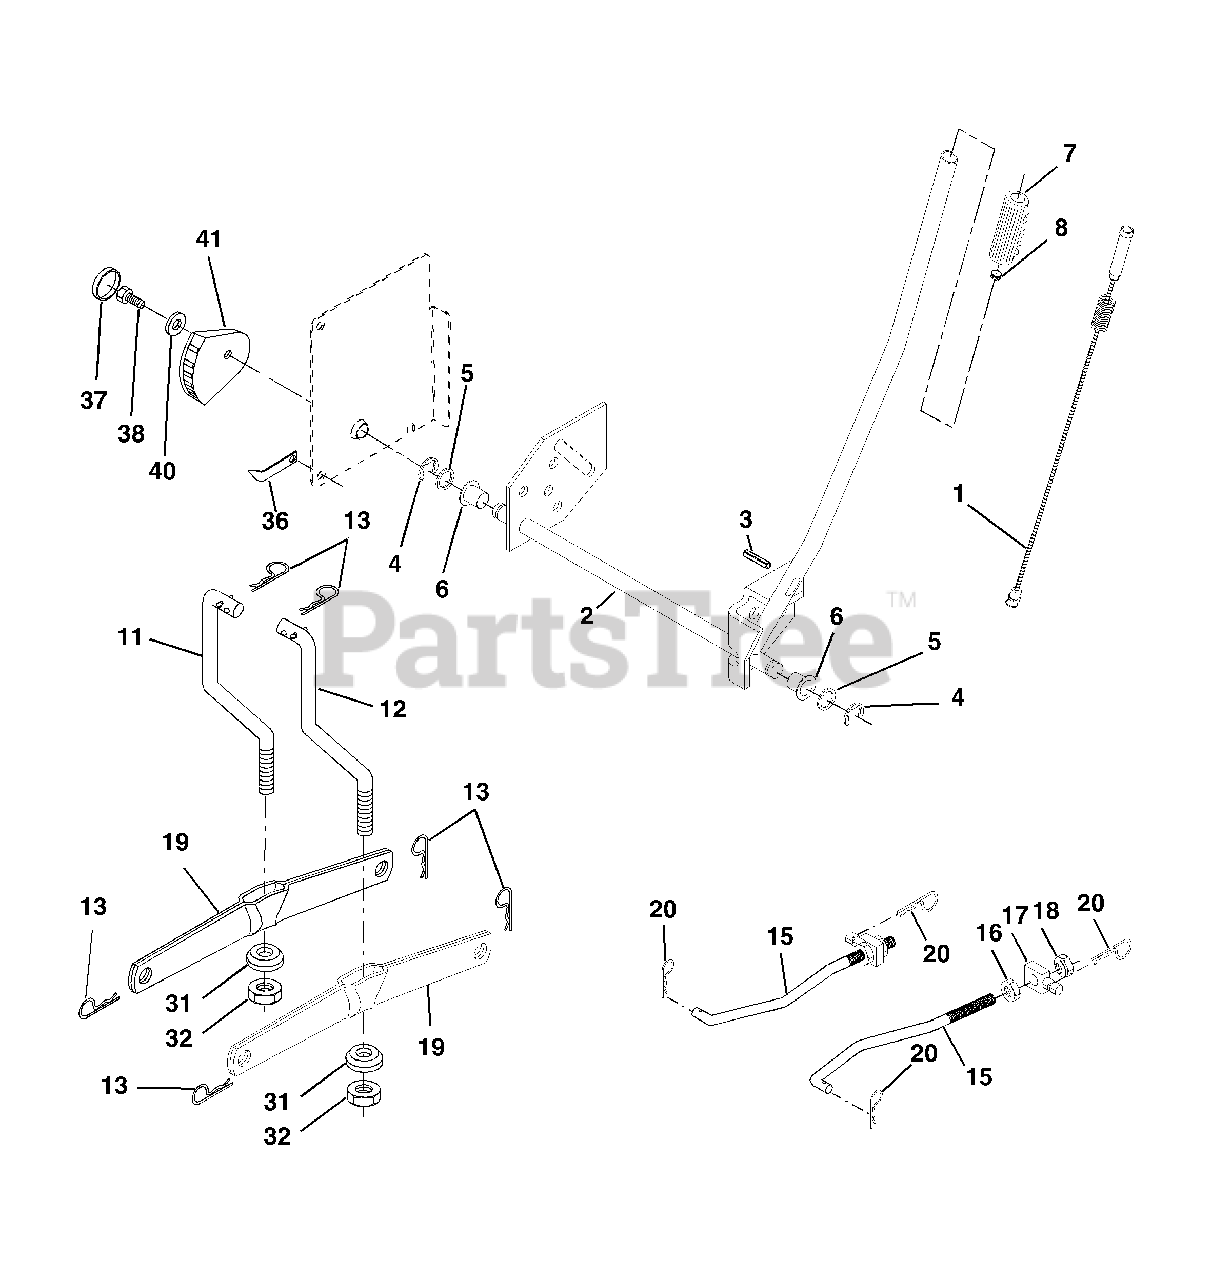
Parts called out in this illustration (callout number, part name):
1	Wire Asm Inner/Sprg W/plunger LT
2	Shaft Asm Lift RH w/Inf
3	Pin Groove 1 500 Zinc
4	E Ring #5133-62
5	Washer 21/32 X 1 X 21 Ga
6	Bearing Nylon Blk 629 Id
7	Grip Handle
8	Button Plunger Yellow
11	Link Lift LH Fixed Length
12	Link Lift RH Fixed Length
13	Retainer Spring
15	Link Front
16	Nut Jam Hex 1/2-13 Unc
17	Trunnion
18	Nut Lock w/Wsh 1/2-13 Unc
19	Arm Suspension Rear
20	Retainer Spring
31	Bearing Pvt Lift
32	Nut Crownlock 3/8 - 24
36	Pointer Height Indicator
37	Plug Hole Blk 1.485/1.515 Dia.
38	Screw Thdrol 5/16-18 x 1
40	Washer 11/32 x 1-1/2 10 Ga.
41	Indicator Height STLT
